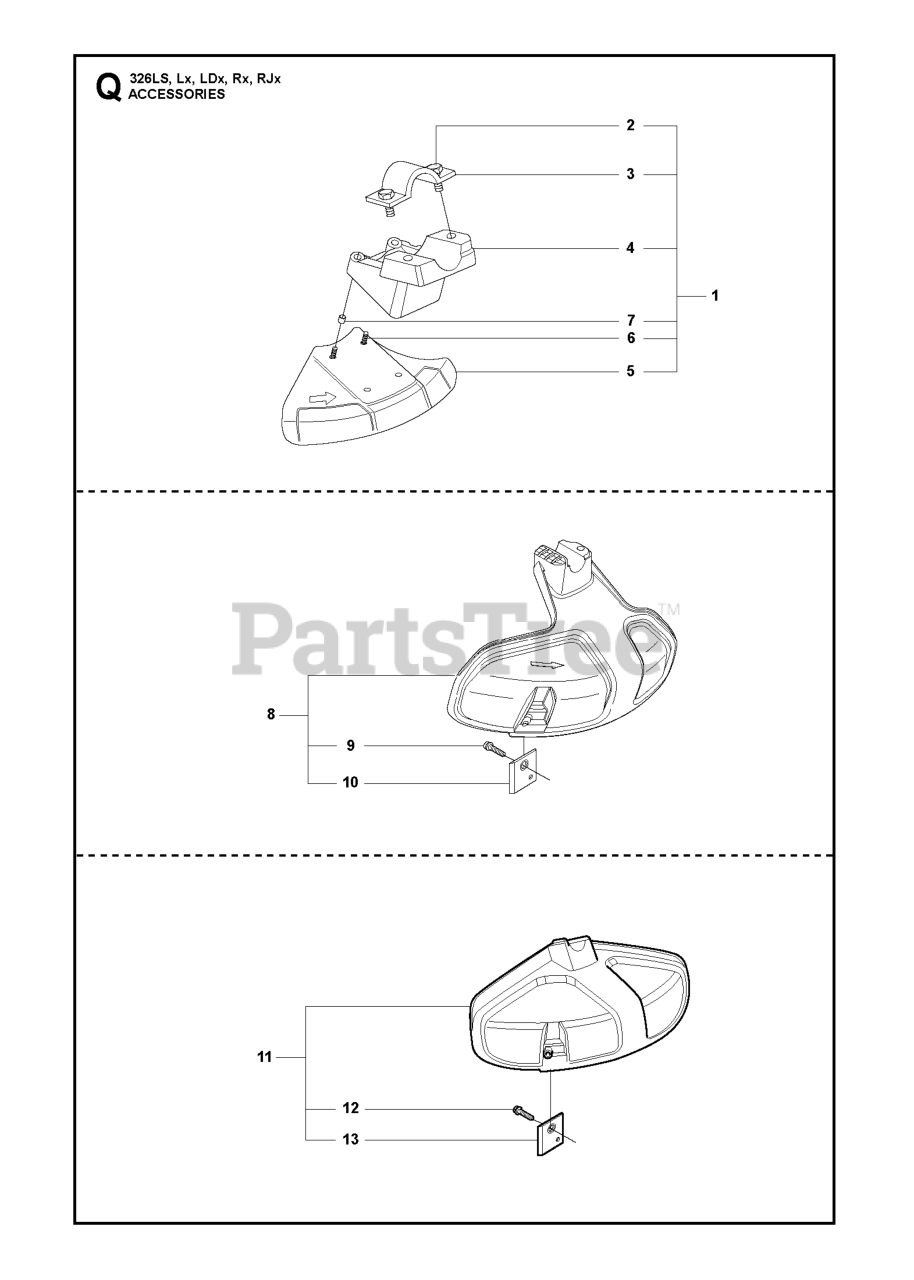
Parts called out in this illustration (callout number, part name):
1	ACCESSORY BAG
2	SCREW IHSCFMO
3	CLAMP ASSY
5	BLADE GUARD
6	SCREW
7	LOCKING NUT
8	TRIMMER GUARD ASSEMBLY
10	LINE CUTTER
11	GRASS SHIELD
13	LINE CUTTER
